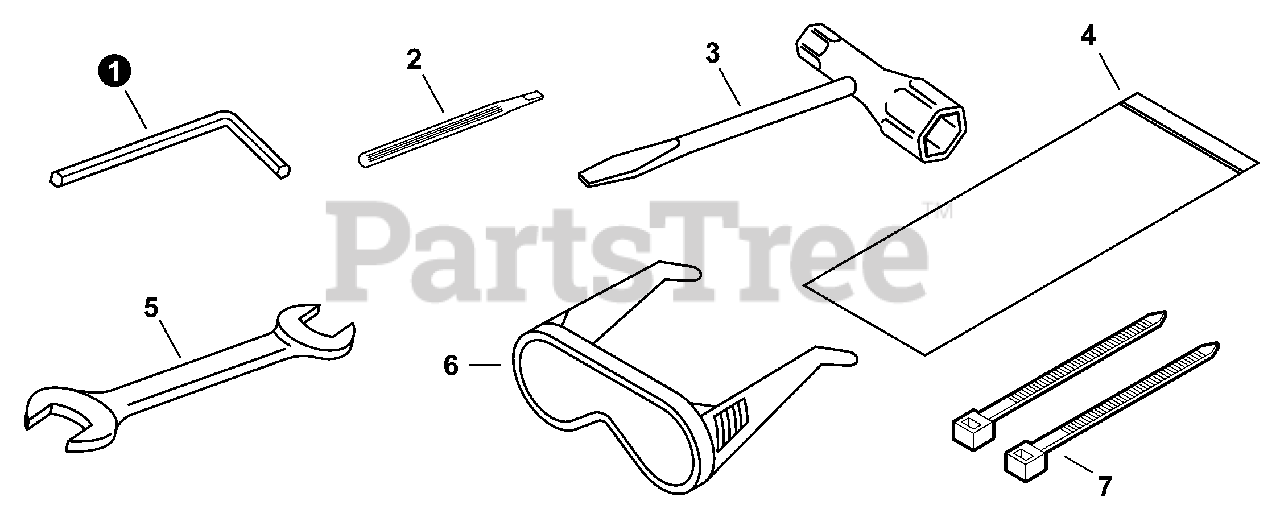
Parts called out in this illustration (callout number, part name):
1	WRENCH, ALLEN 4 MM
2	SCREWDRIVER, PLASTIC
3	T-WRENCH 13×19 MM
4	BAG, TOOL
5	SPANNER 8×10
6	GLASSES, SAFETY
7	TIE, CABLE
